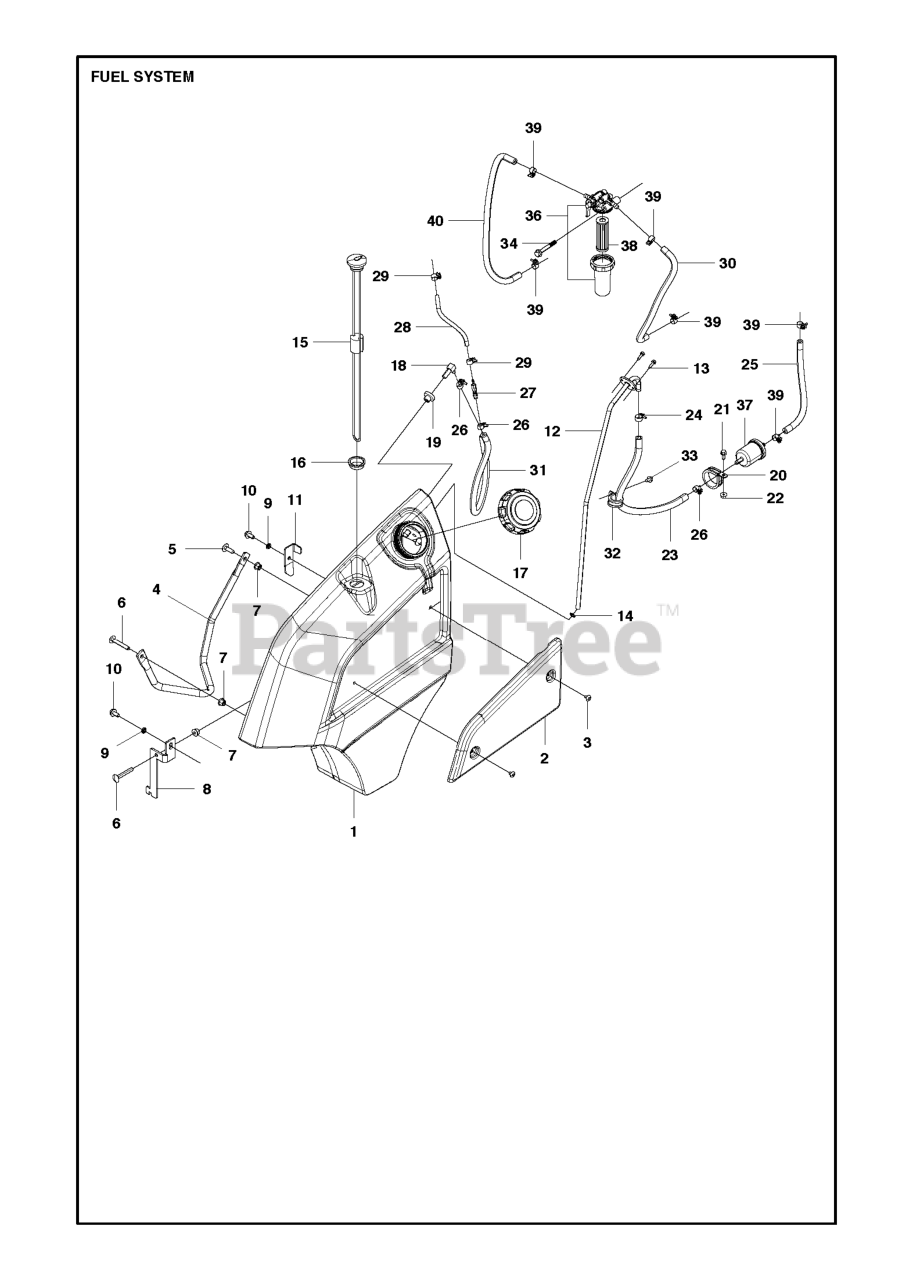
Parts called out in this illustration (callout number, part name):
7	NUT FLANGE
9	WASHER LOCK 8.7X13.5X2.5 ZN FL
17	TANK CAP - DIESEL
19	RUBBER GROMMET
21	SCREW
22	NUT FLANGE
24	HOSE CLAMP FUEL HOSE
26	RP HOSE CLAMP FUEL HOSE
29	HOSE CLAMP FUEL HOSE
32	HOSE CLAMP
39	HOSE CLAMP FUEL
